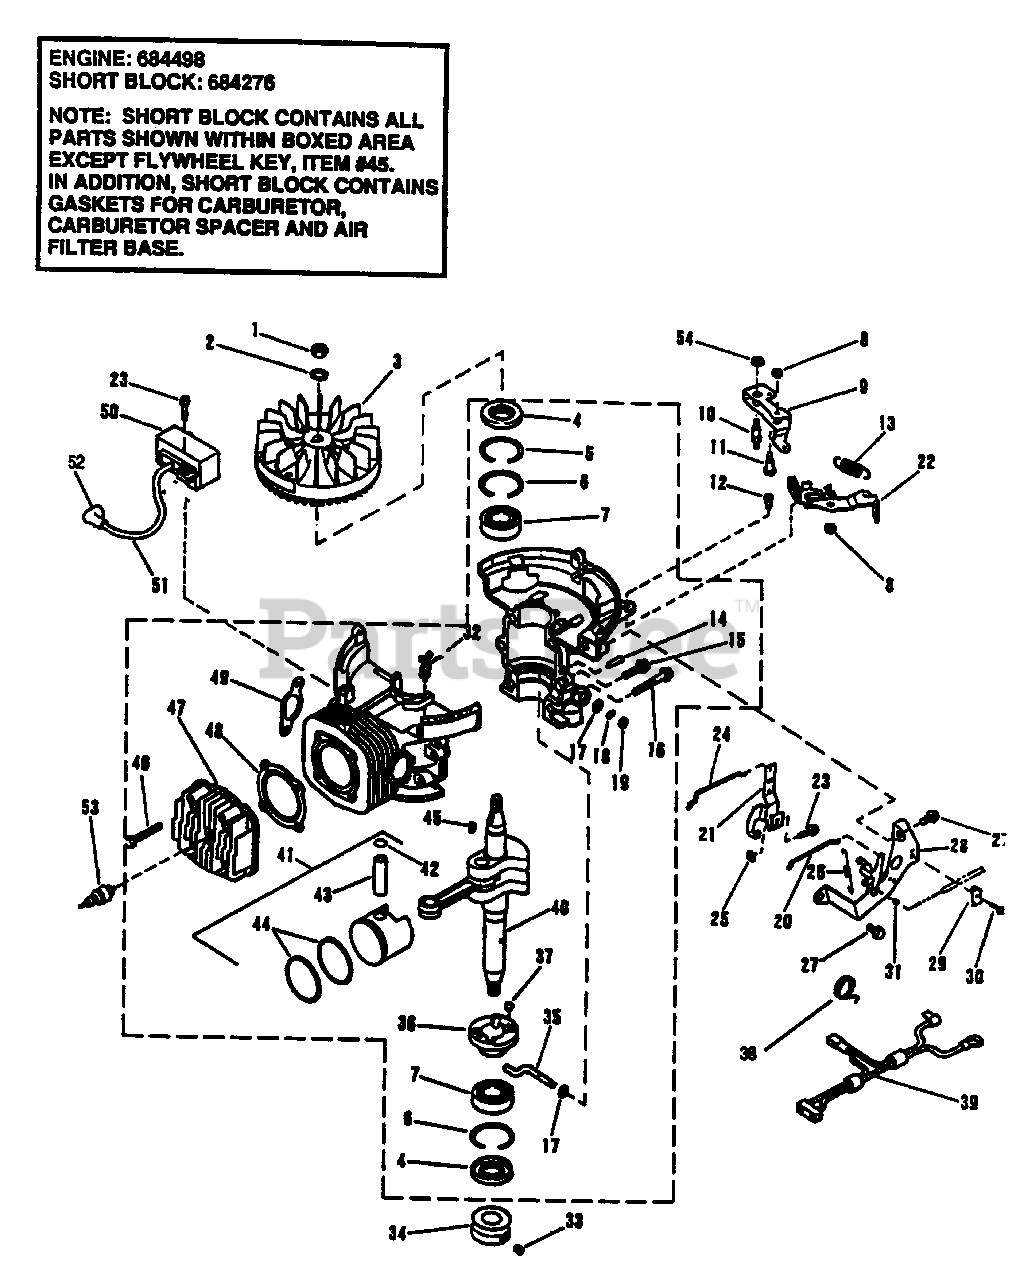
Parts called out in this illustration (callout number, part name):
1	Nut-Flywheel
2	Lockwasher-Flywheel
3	Flywheel
4	Oil Seal-Crankshaft
5	Retaining Ring
6	Retaining Ring
7	Bearing-Crankshaft
8	Locknut
9	Brake Actuator Lever
10	Shoulder Stud-Actuator Lever
11	Shoulder Bolt
12	Shoulder Bolt
13	Brake Spring
14	Taper Pin
15	Screw-Crankcase
16	Screw-Crankcase
17	Washer-Governor Shaft
18	Retainer Ring-Governor Shaft
19	Oil Seal-Governor Shaft
20	Choke Rod
21	Governor Control Lever
22	Brake & Switch Kit
23	Screw
24	Throttle Rod
25	Nut-Governor Lever
26	Governor Spring
27	Screw-Governor Bracket
28	Governor Bracket Assy (Inc. 38)
29	Clamp-Throttle Cable Brkt.
30	Screw-Cable Bracket
31	Throttle Control Wire Retainer
32	Wire Tie
33	Set Screw-Pulley (680523)
34	Engine Pulley (680523)
35	Governor Shaft
36	Governor Ramp
37	Governor Ball
38	Torsion Spring
39	Wire Harness
40	Crankshaft & Connecting Rod
41	Piston and Ring Assy. (Standard) (Inc. 42-44)
42	Retaining Ring
43	Wrist Pin
44	Ring Set (Standard)
45	Key-Flywheel
46	Screw-Cylinder Head to Block
47	Cylinder Head
48	Head Gasket
49	Exhaust Gasket
50	C.D. Ignition Module
51	High Tension Lead & Cvr (Inc. 52)
52	Cover & Terminal Assembly
53	Spark Plug
54	Hex Flange Nut
